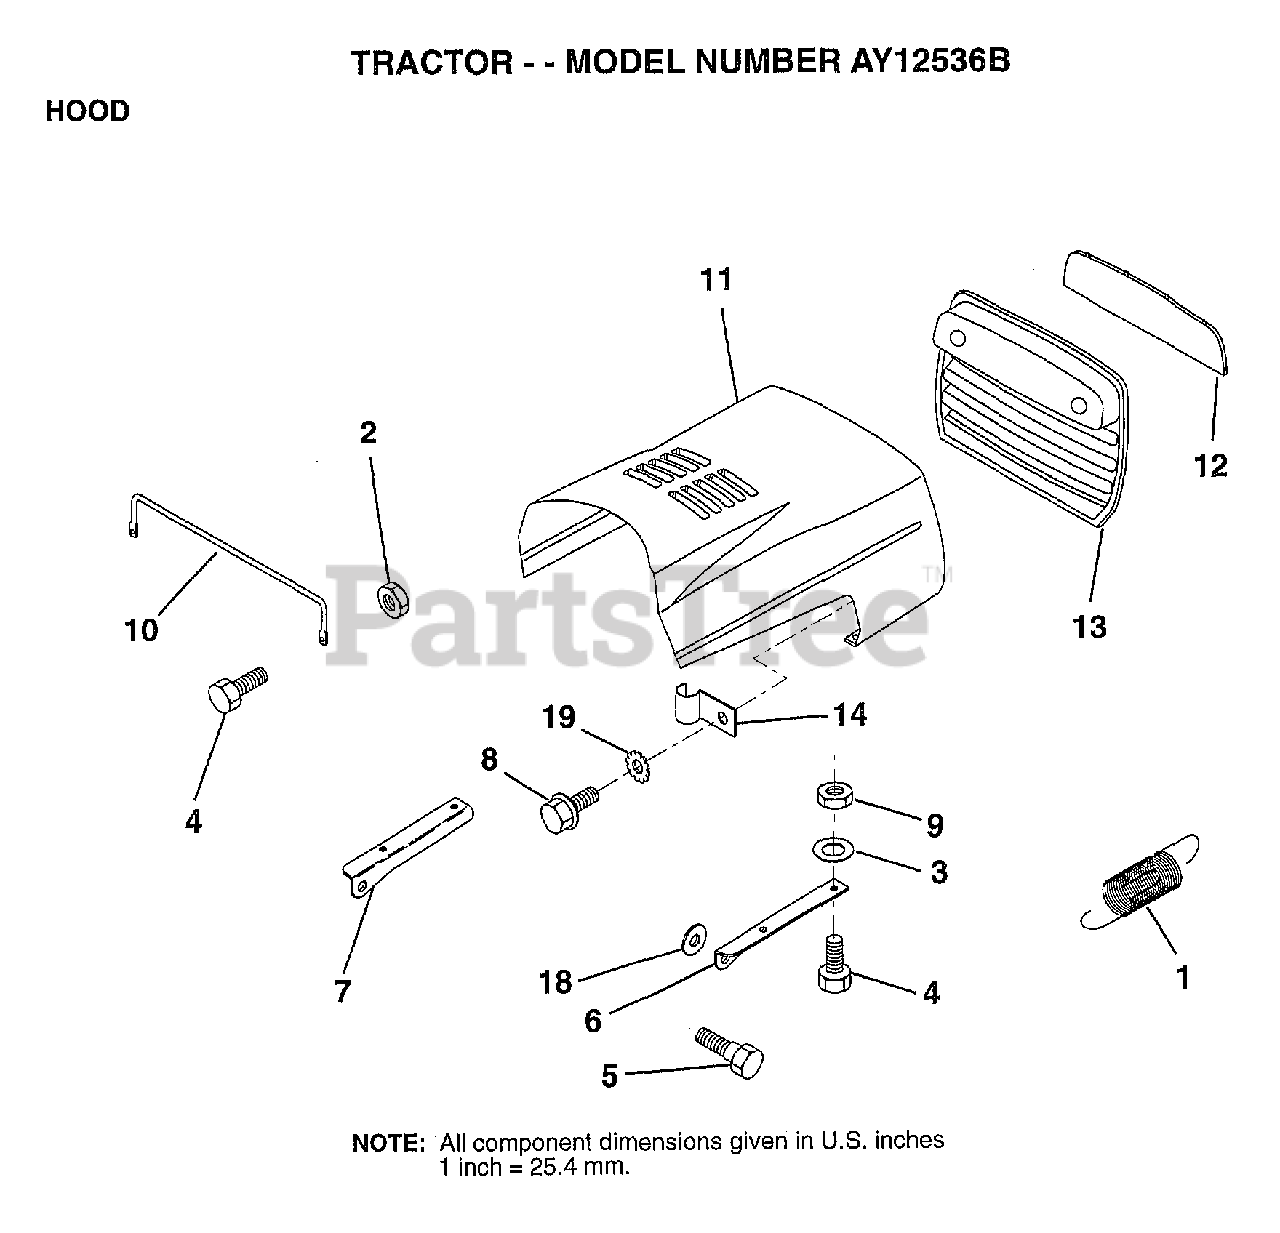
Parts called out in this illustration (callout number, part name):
1	EXT SPRING
2	NUT HXKEP 1/4X20
3	WASHER
5	BOLT.SHLD.5/16-18
6	BRKT HOOD RH
7	BRKT HOOD LH
8	SCREW SLTD HXHD
9	NUT
10	"BRACE,HOOD"
11	HOOD.IMPREG.MS550
12	LENS
13	GRILL
14	CLIP T
18	WASHER
19	LOCKWASHER GT
